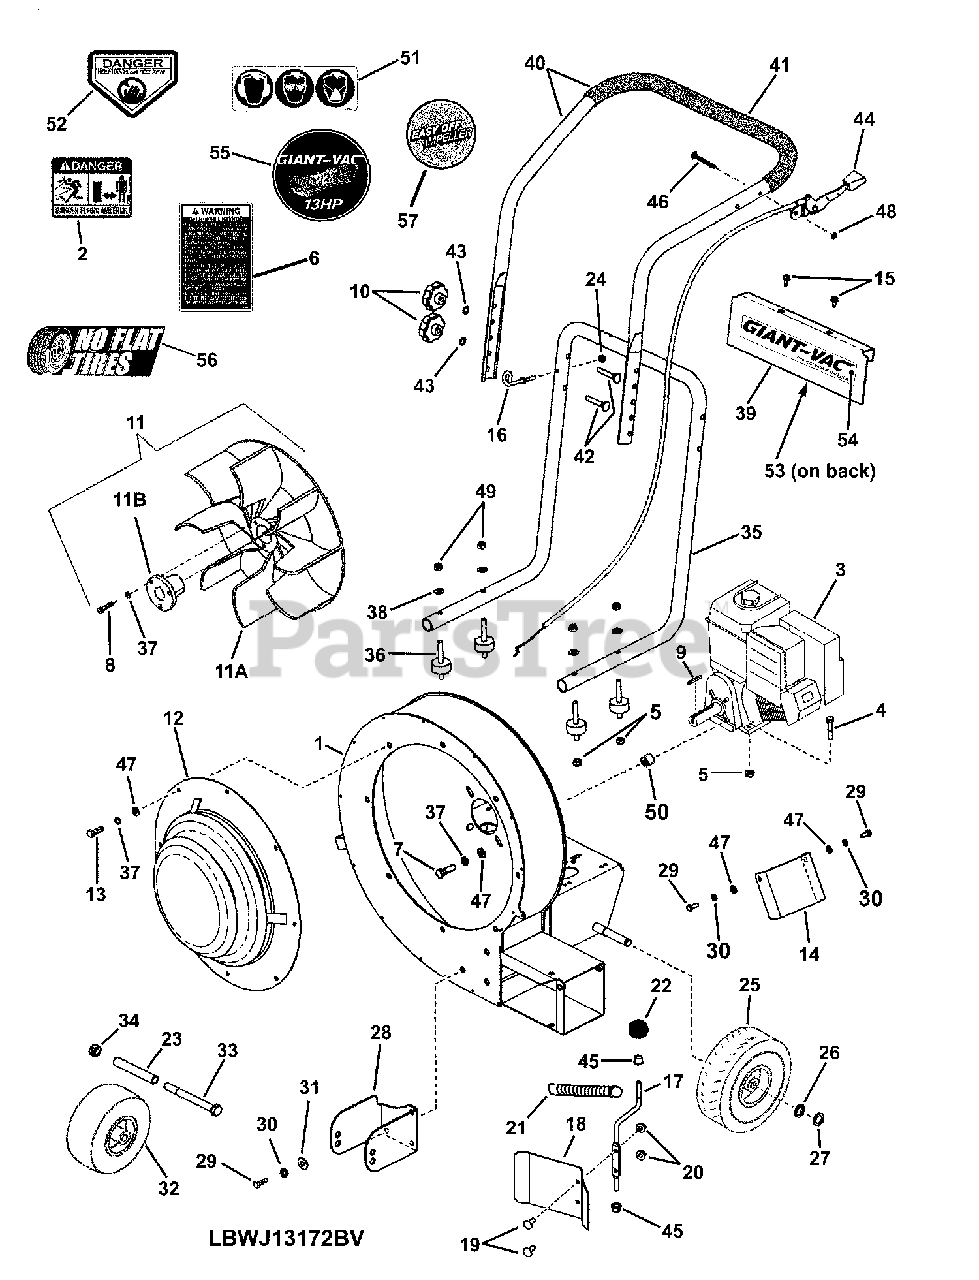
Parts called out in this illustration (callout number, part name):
1	WELDMENT, Housing- 13BWJ (shown)
2	DECAL, Thrown Objects, Large
3	*ENGINE, 13HP Briggs Vanguard
4	SCREW, 5/16-18 x 1-1/2 Hex Head Cap, GR5
5	NUT, 5/16-18 Hex Flange Lock, GR 5
6	DECAL, Warning- Leaf Blower
7	SCREW, 5/16-24 x 1-3/4" Hex Head Cap, GR 5
8	SCREW, 5/16-18 x 1-1/4", Hex Head Cap, GR 5
9	KEY, 1/4" Square x 2"
10	KNOB, Fluted- Folding Handles (5/16-18 thread)
11	ASSY, 17" Permanent Impeller
11A	IMPELLER, Aluminum 17" O.D., 9 Curved Blades
11B	**HUB, Taper-Lok (1.938 OAL)
12	WELDMENT, Intake Baffle- WJ- 17"
13	SCREW, 5/16-18 x 3/4" Hex Head Cap, GR 5
14	DEFLECTOR, Side Air- WJ- 17"
15	SCREW, 5/16-18 x 5/8" Hex Washer Self-Tap
16	GUIDE, Rope (1/4-20 thread)
17	ROD, Door Front/Side Discharge
18	DOOR, Forward Air Control- WJ
19	SCREW, Carriage 1/4-20 x 3/4" GR 5
20	NUT, 1/4-20 Hex Flange Lock, GR 5
21	SPRING, Extension
22	KNOB, Ball Hand Lever- 3/8-16 Metal Insert
23	SLEEVE, Axle
24	NUT, 1/4-20 Hex Center Lock, GR 5 or B
25	ASSY., Wheel & Tire 410/350-4 "Flatfree"
26	WASHER, .64 x .99 x .05 Flat
27	RING, External Retaining (TRU1500-62)
28	BRACKET, Front Wheel Mounting
29	SCREW, 3/8-16 x 1" Hex Head Cap, GR 5
30	WASHER, 3/8" Split Lock
31	WASHER, 3/8" Flat
32	ASSEMBLY, Tire & Wheel 9 x 350-4 "Flatfree"
33	BOLT, 1/2-13 x 5" Hex Head Cap
34	NUT, 1/2-13 Hex Center Lock, GR 5
35	HANDLE, Lower Folding- Wide- Blower
36	MOUNT, Vibration (5/16-18 thread- both ends)
37	WASHER, 5/16" Split Lock
38	WASHER, 5/16" Curved
39	DASH PANEL, Blower- Wide
40	ASSY, Upper Handle & Grip- Wide
41	GRIP, 1.0 x 21-1/2" Foam
42	BOLT, 5/16-18 x 2", Curved Head Square Neck, GR 2
43	WASHER, 5/16" Internal Tooth Lock
44	THROTTLE CONTROL, 29.25/2.12
45	BEARING, 3/8" Clip
46	SCREW, 1/4-20 x 2" Hex Head Cap, GR 5
47	WASHER, .34 x .69 x .08 Flat
48	NUT,1/4-20 Hex Nyloc
49	NUT, 5/16-18 Hex Nyloc
50	SPACER, .375 I.D. x .750 O.D. x .500
51	DECAL, Personal Protection
52	DECAL, Danger, Cut Finger
53	DECAL, GIANT-VAC (Small)
54	DECAL, GIANT VAC
55	DECAL, 13 HP Whisper Jet
56	DECAL, No Flat Tire
57	DECAL, Easy Off Impeller
